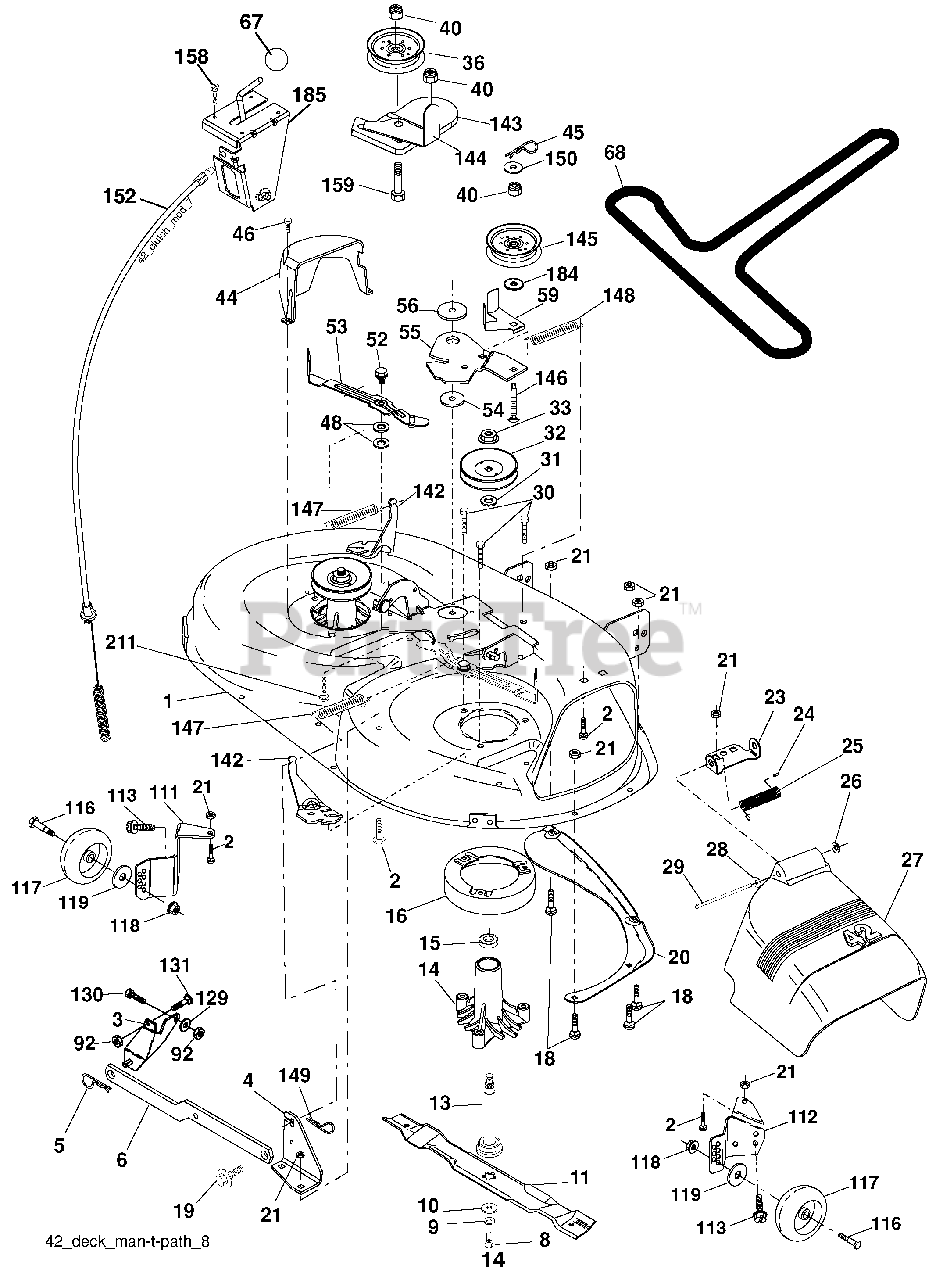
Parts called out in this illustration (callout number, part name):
1	Mower Deck Assembly, 42"
2	Bolt
3	Bracket Asm Fr. Sway Bar 3/42
4	Bracket Asm Deck 42" Sway Bar
5	Retainer Spring
6	Bar Sway Deck
8	Bolt 3/8-24 x 1.25 Gr. 8 patched
9	Washer, Lock
10	Washer, Hardened (The following Blades are available)
11	Blade Mower 42” Hi-Lift (for bagging and discharging)
11	Blade, Mulching 42” Std (for mulching mowers only)
11	Blade Mulching 42” Premium (For better wear when mulching)
13	Shaft As sem bly, Mandrel, Vented
14	Housing, Mandrel, Vented
15	Bearing, Ball, Mandrel
16	Stripper, Mandrel Deck
18	Bolt, Carriage 5/16-18 x 5/8
19	Bolt, Shoulder
20	Baffle, Vortex
21	Nut
23	Bracket, Deflector Mower 42"
24	Cap, Sleeve 80 x 112 Blk Mower
25	Spring, Torsion, Deflector 2 52
26	Nut, Push Phos & Oil
27	Shield, Deflector 42" Blk
28	Washer 11/32 x 5/8 x 16 Ga.
29	Rod, Hinge 42" 6 75 W/G
30	Screw Thdrol
31	Washer, Spacer Mower Vented
32	Pulley, Mandrel
33	Nut, Toplock
36	Pulley, Idler, Flat
40	Nut Lock 3/8-16
44	Guard, Mandrel, LH
45	Retainer
46	Screw, Thdrol 1/4-20 x 5/8 T
48	Washer, Hardened
52	Bolt, Shoulder 5/16-18 unc
53	Arm Assembly, Pad, Brake
54	Washer, Hardened
55	Arm, Idler
56	Spacer, Retainer
59	Guard TUV Idler
67	Knob Round
68	V-Belt, 42" Mower
92	Nut Lock Hex
111	Bracket Wheel Gauge LH
112	Bracket Wheel Gauge RH
113	Blt 5/16-18 Hex
116	Bolt SHLD
117	Wheel Gauge
118	Nut Centerlock 3/8-16
119	Washer 3/8 x 7/8 x 14 Ga.
129	Washer 13/32 x 13/16 x 12 Ga.
130	Bolt Fin Hex
131	Bolt RDHD SQNK
142	Arm Spring Brake Mower
143	Bracket Arm Idler 42"
144	Keeper Belt 42" Clutch Cable
145	Pulley Idler Flat
146	Bolt Carriage Idler
147	Spring Extension
148	Spring Return Idler
149	Retainer Spring Yellow
150	Washer 9/32 x 3/4 x 10 Ga.
152	Clutch Cable 42"
158	Screw Hex Thd Cut 1/4-20 x 1/2
159	Bolt Rdhd Sqn 3/8-16 unc x 1-3/4
184	Washer 13/32 x 7/8 x 10 Ga.
185	Head Asm Cable Clutch
211	Bolt Carr SH 3/8-16 x 1-1/2 Gr.5
211	Mandrel Assembly
211	Replacement Mower, Complete
